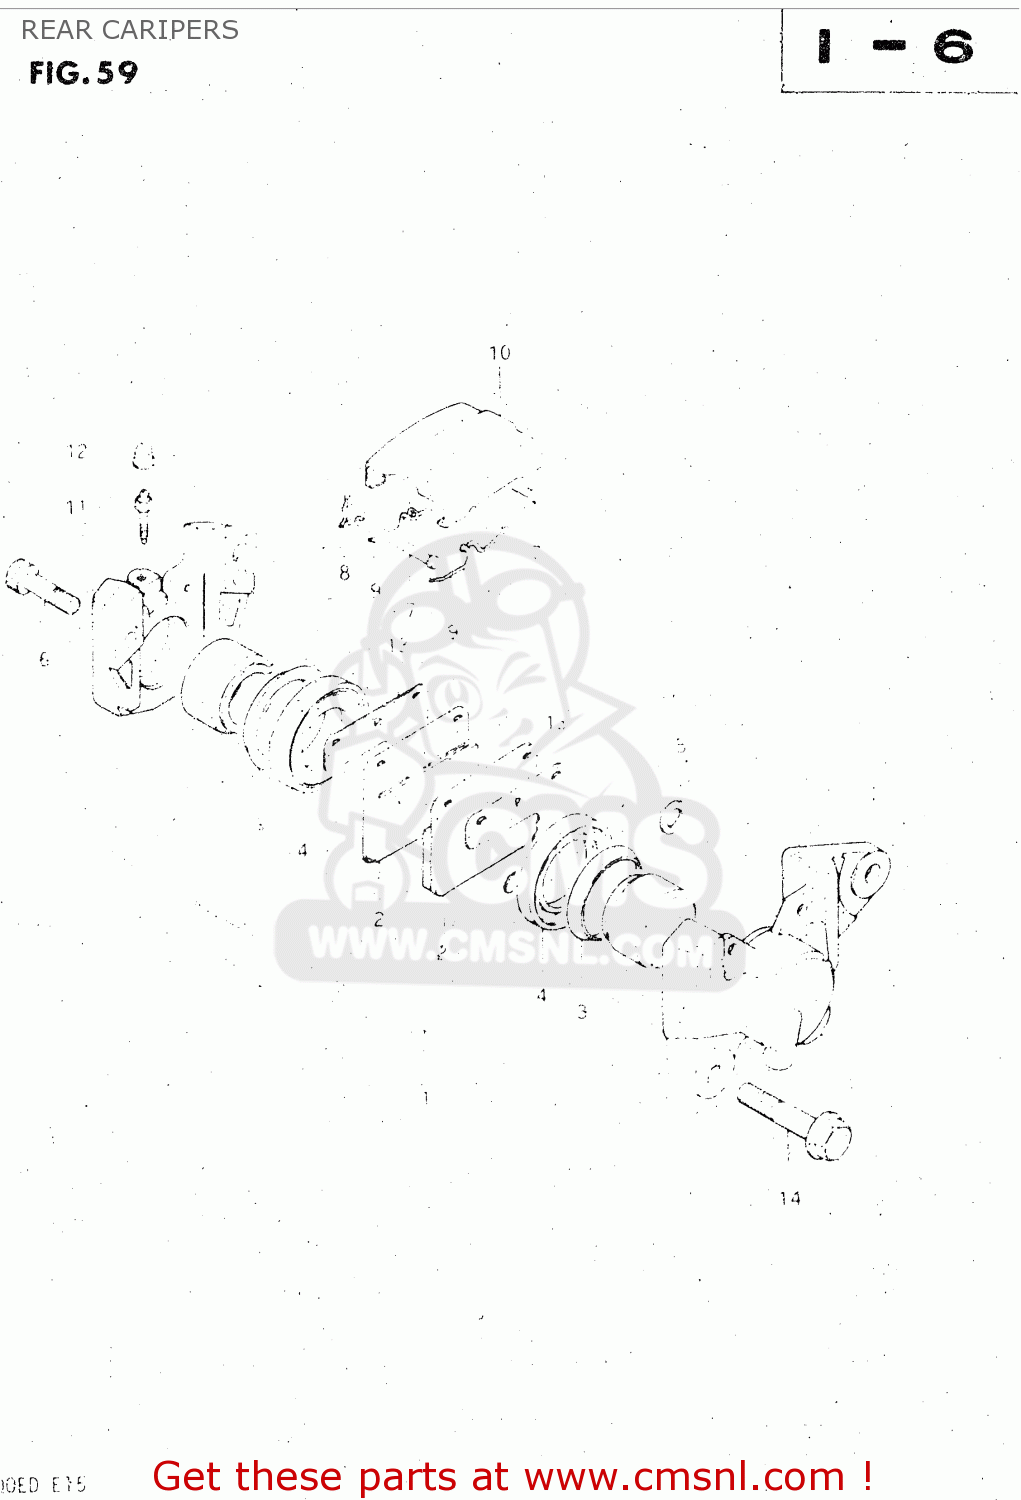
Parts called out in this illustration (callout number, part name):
1	PISTON SET
2	PAD,BRAKE
3	SEAL,PISTON
4	BOOT,PISTON
5	SEAL,JOINT
6	BOLT,CALIPER HOUSING
7	PIN,PAD
8	CLIP,PAD PIN
9	SPRING
10	COVER,DUST
11	BLEEDER
12	CAP,BREATHER
13	SHIM,RR CALIPER
14	BOLT
